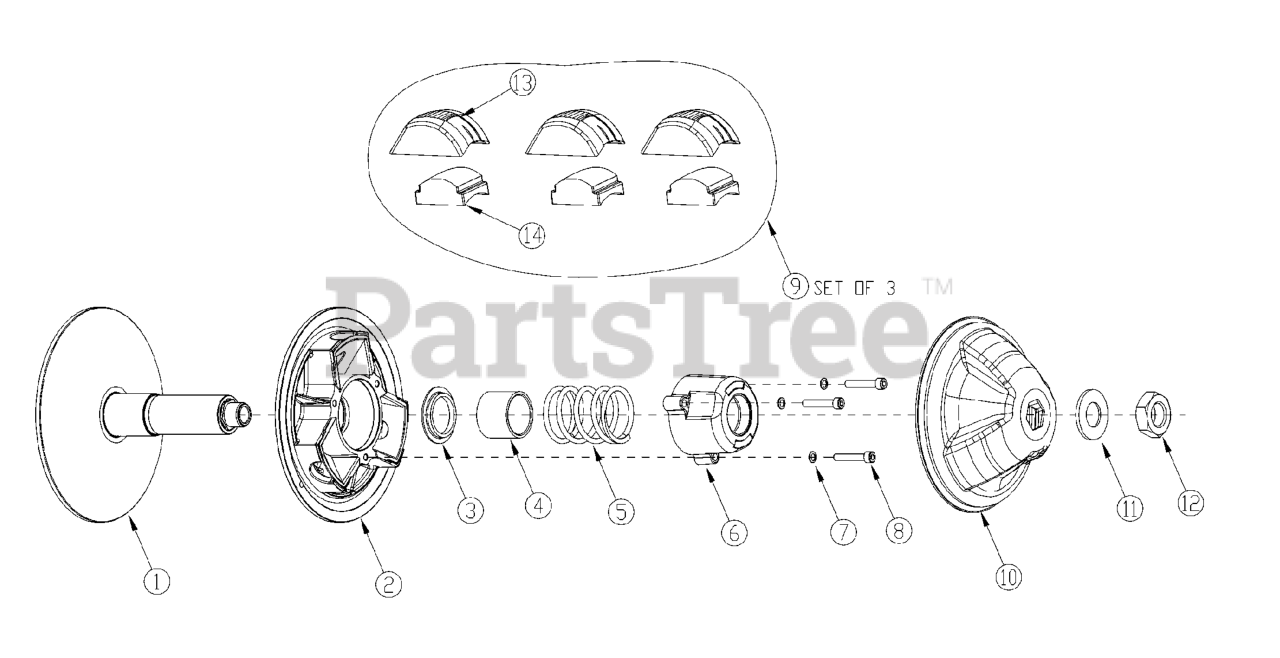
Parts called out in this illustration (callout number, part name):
1	FIXED FLANGE
2	SLIDING FLANGE
3	SPRING SUPPORT
4	STROKE LIMITER
5	SPRING
6	SPRING COVER
7	LOCK WASHER
8	SOCKET HEAD CAP SCREW
9	BLOCK ASSEMBLY
11	FLATWASHER #10 ZP SAE 44632
12	NUT HEX 7/8-14 PLT
13	BLOCK
14	WEIGHT
